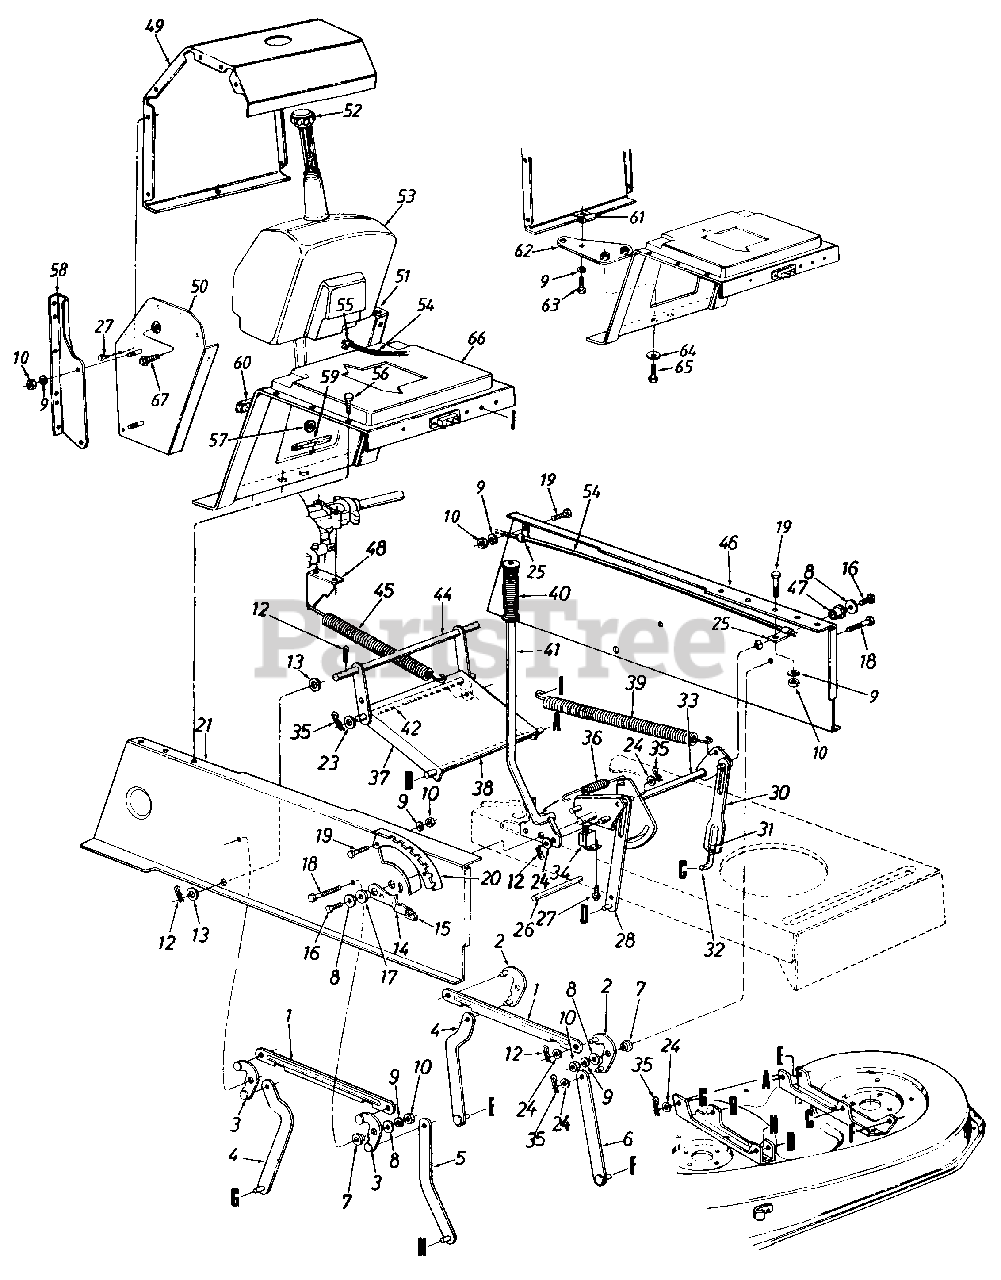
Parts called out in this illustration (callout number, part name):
1	Connecting Rod
2	Pivot Link Ass'y. L.H.
3	Pivot Link Ass'y. R.H.
7	Shld. Spacer .3/8" I.D.
8	Fl-Wash. .344" I.D. x 1.125"
9	L-Wash. 5/16" I.D.
10	Hex Nut 5/16-18 Thd.
12	Cotter Pin 1/8" Dia.
13	Fl-Wash. .635" I.D. x 1.0" O.D.
14	Deck Lift Down Stop
15	Knob
16	Hex Wash. TT-Tap Scr. 5/16-18 x .75" Lg.
17	Flange Brg. .63" I.D.
18	Hex Wash. TT-Tap Scr. 5/16-18 x .875" Lg.
19	Hex Bolt 5/16-18 x .75" Lg.
20	Index Brkt.
21	Upper Frame R.H.
23	Fl-Wash. .385" I.D. x .87" O.D.
24	Fl-Wash. .531" I.D. x .93" O.D.
25	Clamp
26	Running Board Rod
27	Truss Mach. Scr. #10 x .5" Lg.
31	Hex Nut 1/2-20 Thd. (Grade 5)
32	Lift Link Adjuster
33	Lift Shaft Ass'y.
34	Safety Switch (Deck)
35	Inter. Cotter Pin 3/8" Dia.
36	Extension Spring
37	Stabilizer Bracket
38	Shaft 1/2" Dia. x 10.28" Lg.
39	Extension Spring
40	Grip
41	Deck Lift Handle Ass'y.
42	Shaft 3/8" Dia. x 9.34" Lg.
44	Stabilizer Shaft Ass'y.
45	Extension Spring 7.58" Lg.
46	Upper Frame L.H.
47	Flange Brg. .632" I.D.
48	Spring Retainer Brkt.
49	Gas Tank Housing
50	Side Panel Ass'y. R.H.
53	Gas Tank
54	Fuel Line
55	Hose Clamp
56	Hex Wash. AB-Tap 5/16 x .75" Lg.
57	Rubber Grommet
58	Mtg. Brkt. R.H.
59	Trim Strip
60	Foam Strip
61	Speed Nut
62	Hitch Bar Ass'y.
63	Hex Bolt 5/16-18 x 1.0" Lg. (Grade 5)
64	Bell-Wash. .38" I.D. x .88"
65	Hex Wash. Tap Scr. 3/8-16 x .75" Lg.
66	Hitch Plate
67	Hex Wash. Hd. Tap Scr. 1/4-20 x.38" Lg.
